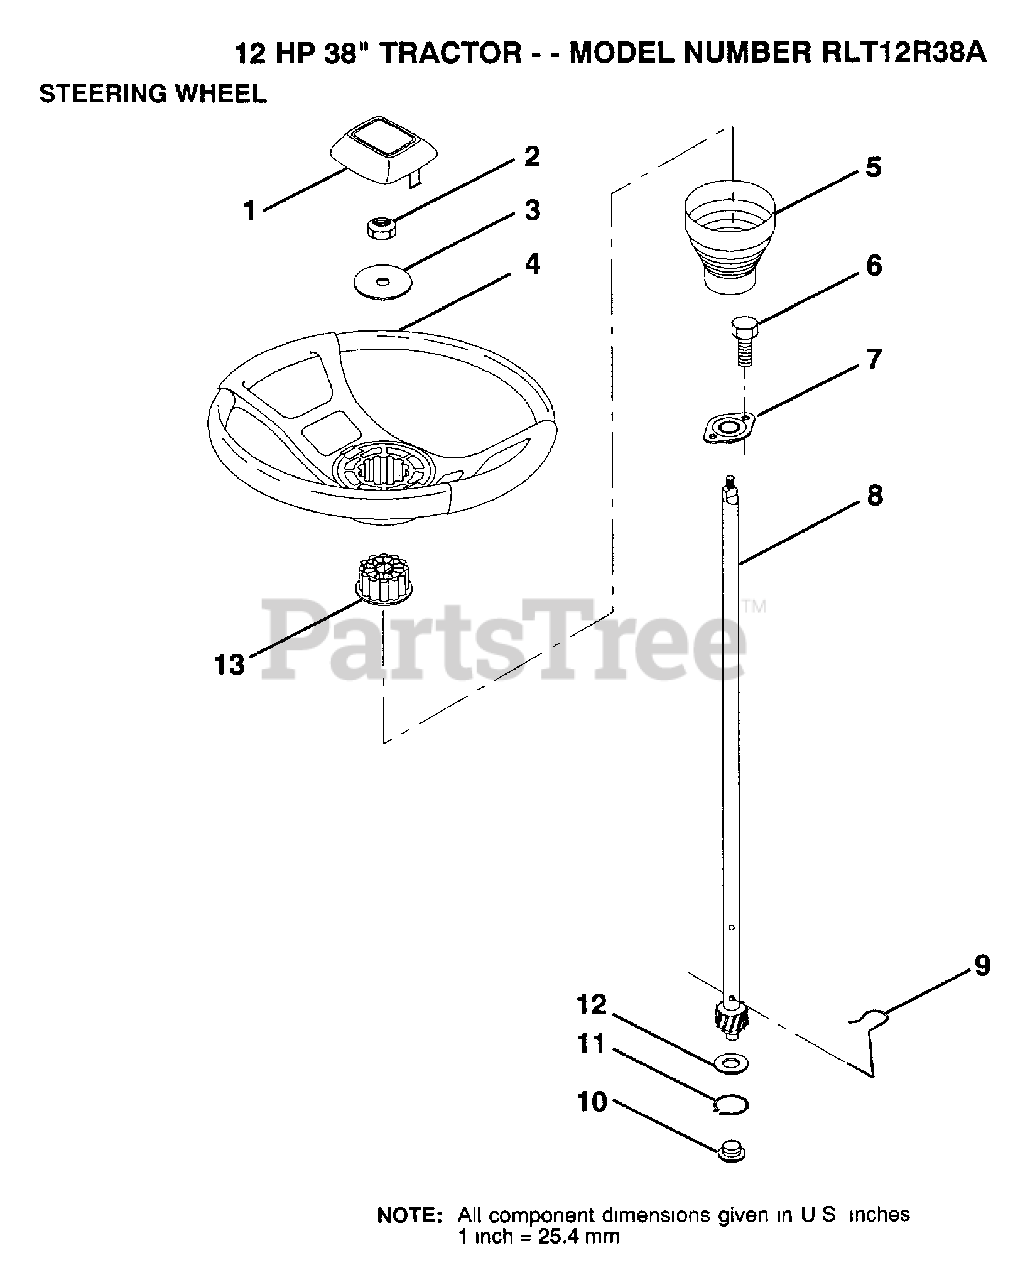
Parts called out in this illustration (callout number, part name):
1	ST WHL INSERT CAP
2	GRIPCO NUT
3	WASHER T
5	SLEEVE STEERING
9	STEERING CLIP
10	BUSHING STEER LWR
11	RING
12	WASHER LT
13	ADAPTER-WHEEL LT
